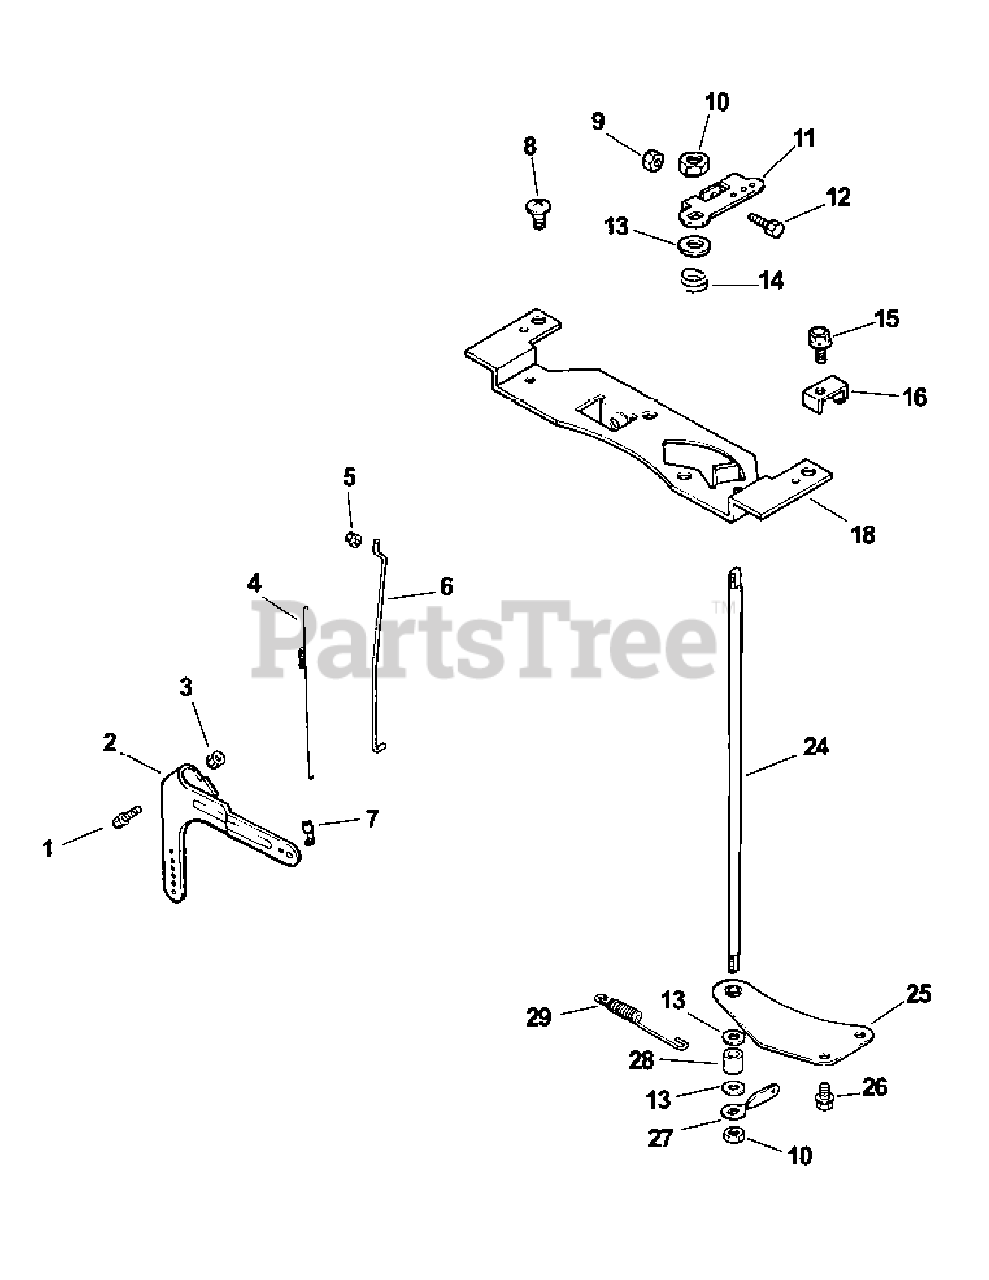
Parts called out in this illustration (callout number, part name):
2	Governor Lever
3	Hex Flange Nut
4	Linkage Spring
5	Linkage Retaining Bushing
6	Throttle Linkage
7	Throttle Linkage Bushing
8	Phillips Screw
10	Hex Lock Nut
11	Throttle Control Lever
12	Hex Cap Screw
13	Plain Washer
14	Throttle Shaft Spring
15	Hex Flange Screw
16	Cable Clamp
18	Control Bracket
24	Throttle Shaft
25	Throttle Shaft Bracket
26	Hex Flange Screw
27	Throttle Control Lever
29	Governor Spring
